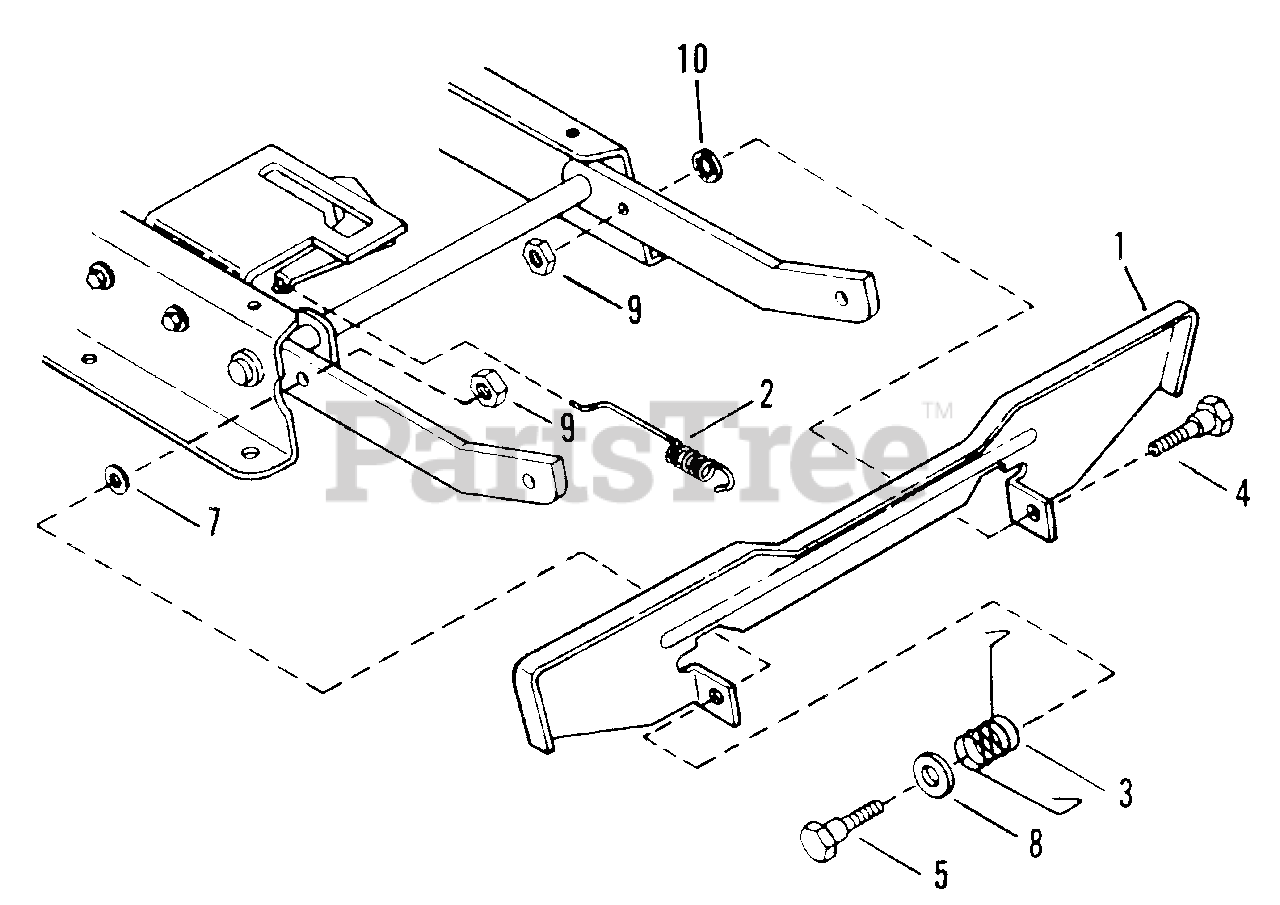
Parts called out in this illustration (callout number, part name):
1	PEDAL, Blade Stop Control
2	SPRING, Latching
3	SPRING, Pedal
4	BOLT, 3/8-24 x 3/4" Shoulder
5	BOLT, 3/8-24 x 9/16" Shoulder
6	ECCENTRIC, Leveling
7	WASHER, 3/8" Flat
8	WASHER, 1/2 Flat
9	NUT, 3/8-24 Hex Lock
10	WASHER, 3/8 Internal Tooth Lock
